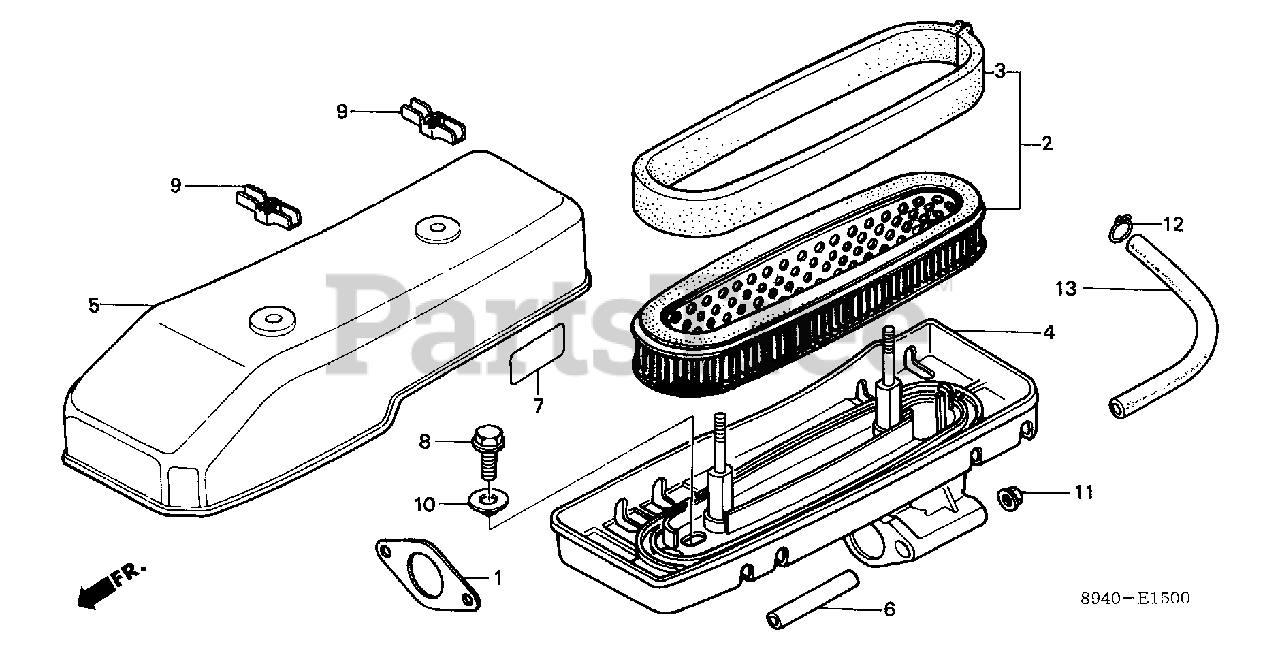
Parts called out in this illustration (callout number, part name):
1	GASKET, AIR CLEANER
2	ELEMENT, AIR CLEANER
3	FILTER (OUTER)
4	HOUSING, AIR CLEANER
5	COVER, AIR CLEANER *NH1* (BLACK)
6	COLLAR, AIR CLEANER HOUSING
7	MARK, AIR CLEANER CAUTION (NOT AVAILABLE)
8	BOLT, FLANGE (6X12) (CT200)
9	WINGNUT, AIR CLEANER COVER
10	WASHER, HEADLIGHT CASE
11	NUT, FLANGE (6MM)
12	CLIP, TUBE (B12.5)
13	BULK HOSE, VACUUM (7.3X1000) (7.5X160)
